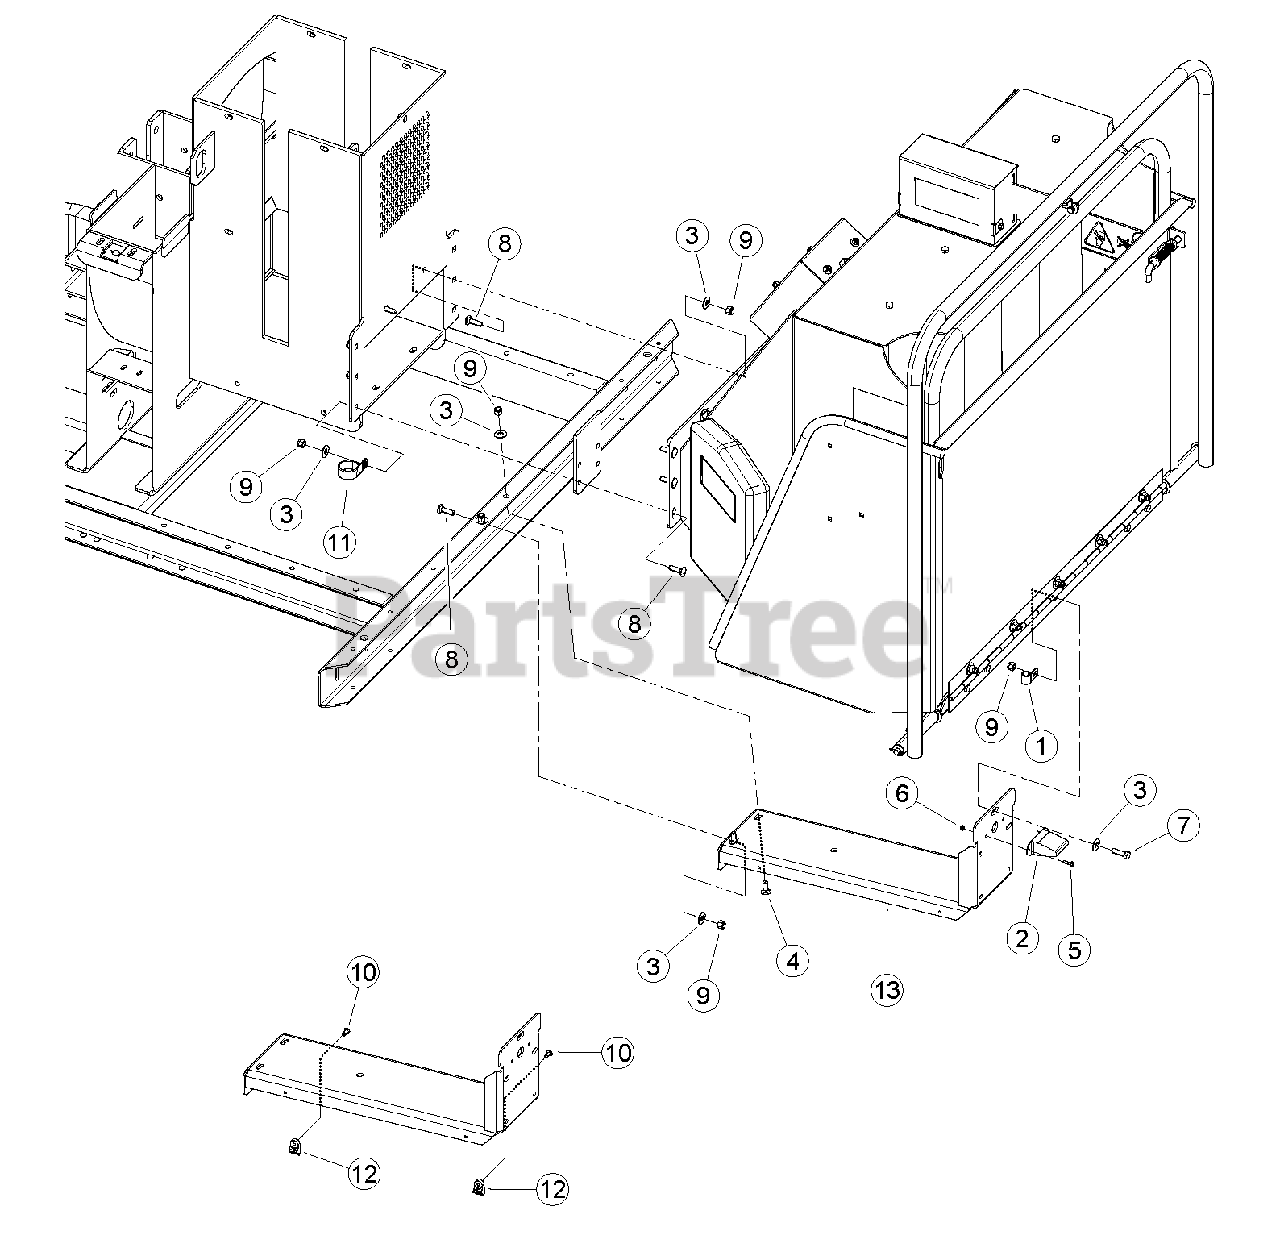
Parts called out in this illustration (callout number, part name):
1	CLAMP, 9/16" COATED
2	LIGHT, LICENSE PLATE
3	WASHER, 3/8 FLAT ZP
4	BOLT, 3/8 X 1 CRG GR5 NC ZP
5	SCREW, #10 X 3/4 HEX TAP SC
6	NUT, 8-32 NYLOCK
7	BOLT, 3/8 X 1-1/4 HEX HD GR5 ZP
8	BOLT, 3/8 X 1-1/4 CRG GR5 NC ZP
9	NUT, 3/8 NE NYLOCK ZP
10	RIVET, AL BLIND 1/4 X 3/4 DOME HEAD
11	CLAMP, 1-9/16" COATED METAL
12	CLAMP, CABLE MOUNT
13	SUPPORT, CHUTE/SPARE
